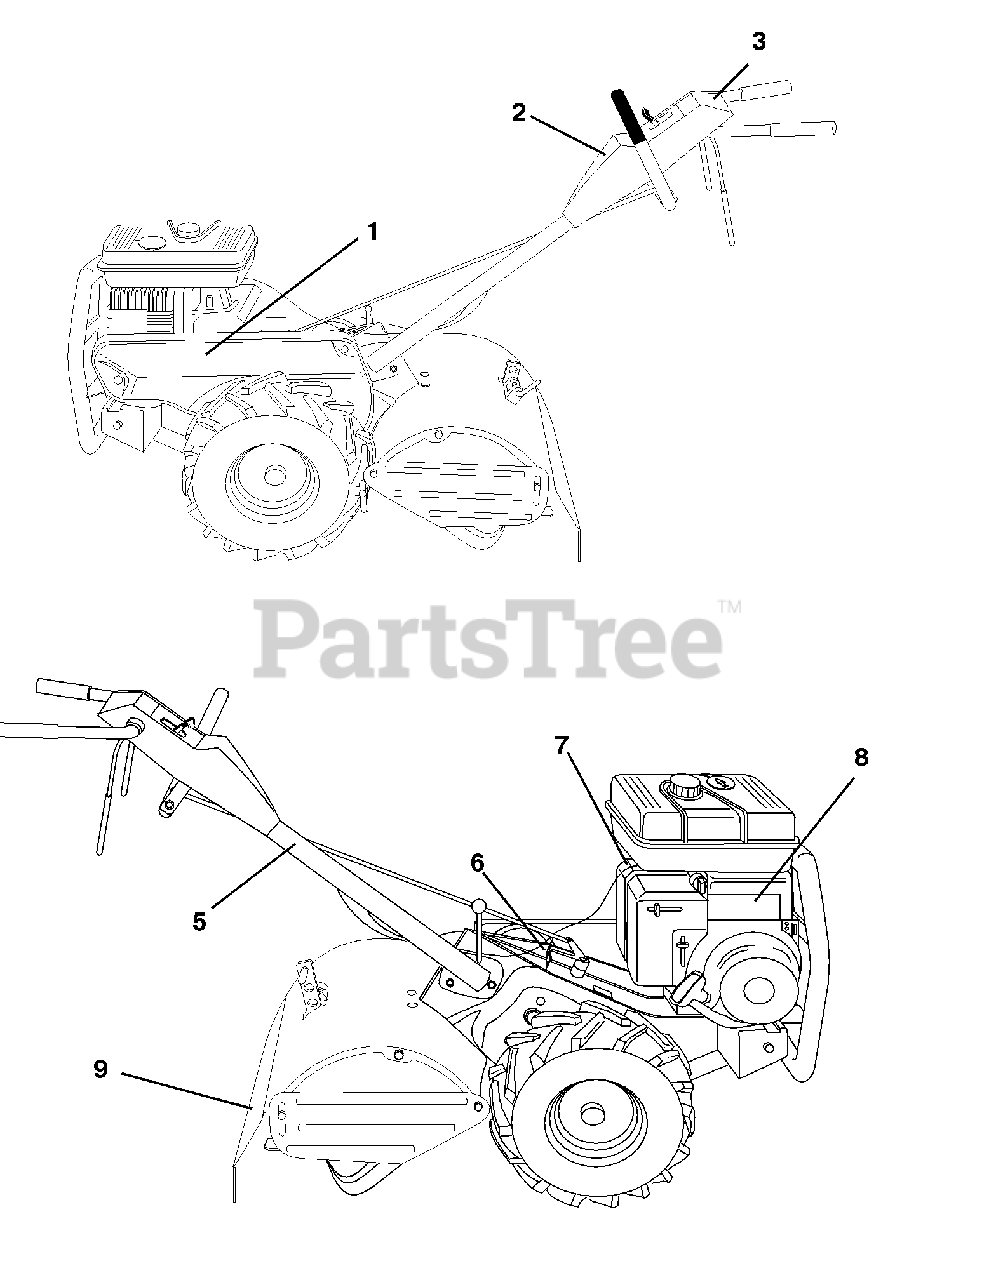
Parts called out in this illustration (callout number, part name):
1	Decal, Logo
2	Decal, Logo
3	Decal, Logo
5	Decal, Hand Placement
6	Decal, Shift Indicator
7	Decal, Caution
8	Decal, Briggs & Stratton
9	Decal, Warning, Rotating Tines
